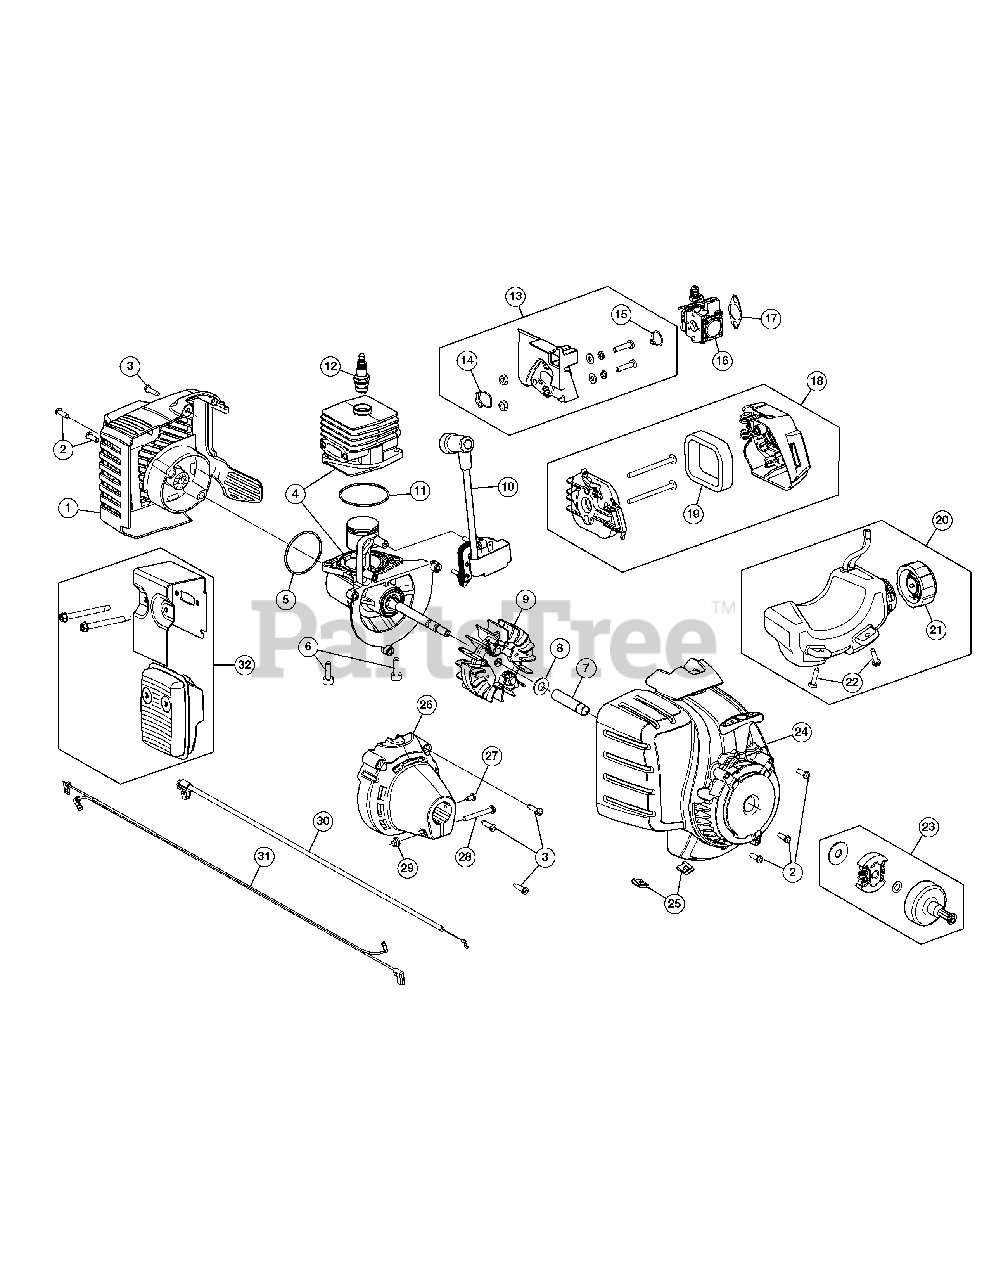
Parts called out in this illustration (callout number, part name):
1	Rear Cover Assembly (Incl. 2 & 3)
2	Cover Screw
3	Housing Screw
4	Short Block Assembly (Incl. 5 - 12)
5	O-Ring
6	Crankcase Bolt
7	Spacer
8	Washer
9	Flywheel Assembly
10	Module Assembly
11	Crankcase O-Ring
12	Spark Plug
13	Insulator Assembly (Incl. 14 & 15)
14	Insulator O-Ring
15	Carburetor O-Ring
16	Carburetor
17	Air Cleaner Gasket
18	Aircleaner Cover Assembly (Incl. 19)
19	Aircleaner Filter
20	Fuel Tank Assembly (Incl. 21 & 22)
21	Fuel Tank Screw
22	Fuel Tank Cap
23	Clutch Assembly
24	Starter Housing (Incl. 3 & 25)
25	U-shaped Nut
26	Clutch Cover (Incl. 2)
27	Anti-rotation Screw
28	Clamp Screw
29	Clamp Nut
30	Throttle Cable
31	Lead Wires
32	Muffler Assembly
